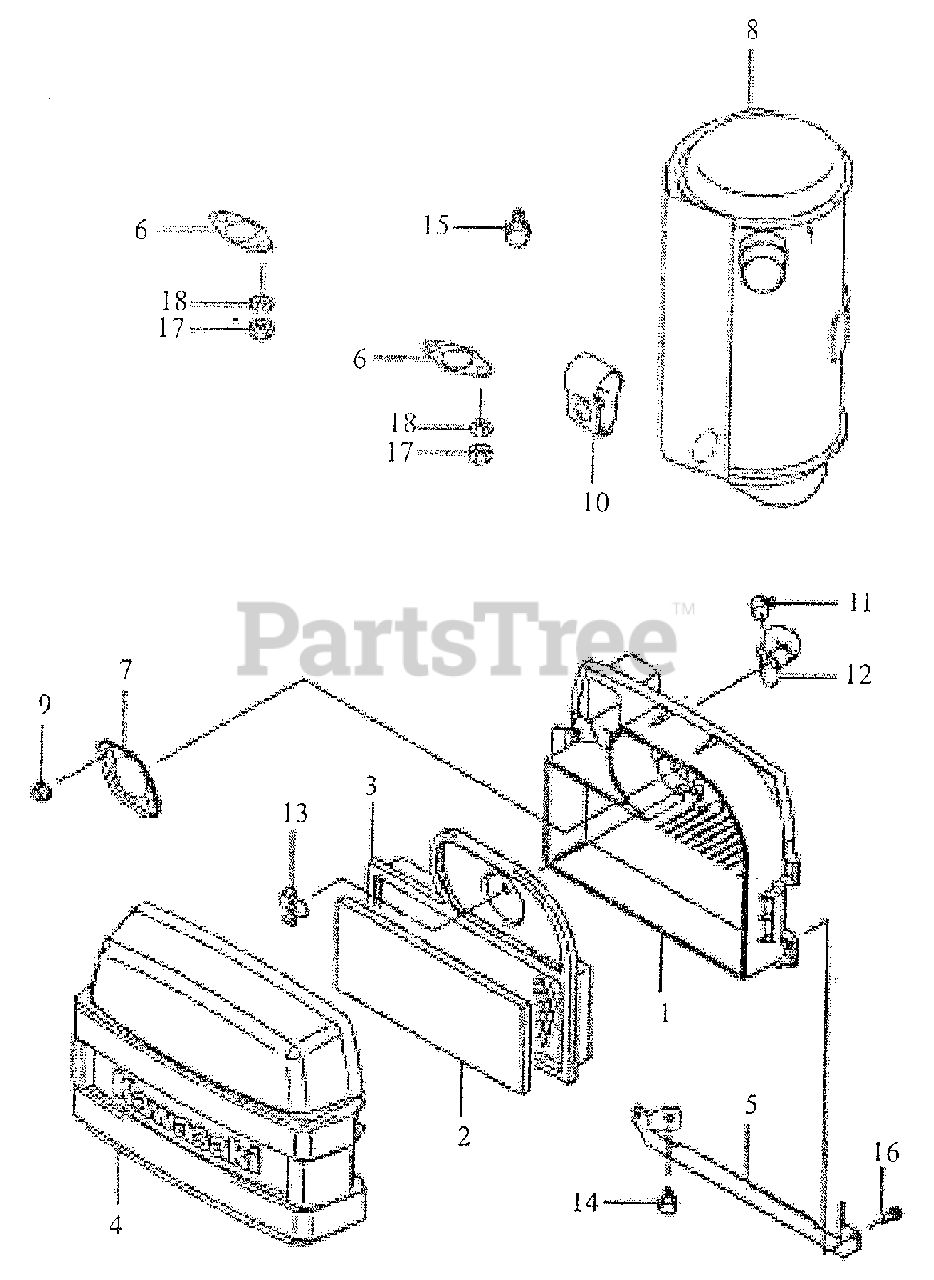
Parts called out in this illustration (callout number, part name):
1	Case, Air Filter
2	Element, Air Pre Filter
3	Element, Air Filter
4	Cover, Air Filter
6	Gasket, Muffler
9	Nut
14	Bolt, Flange
16	Screw
18	Washer, Spring
